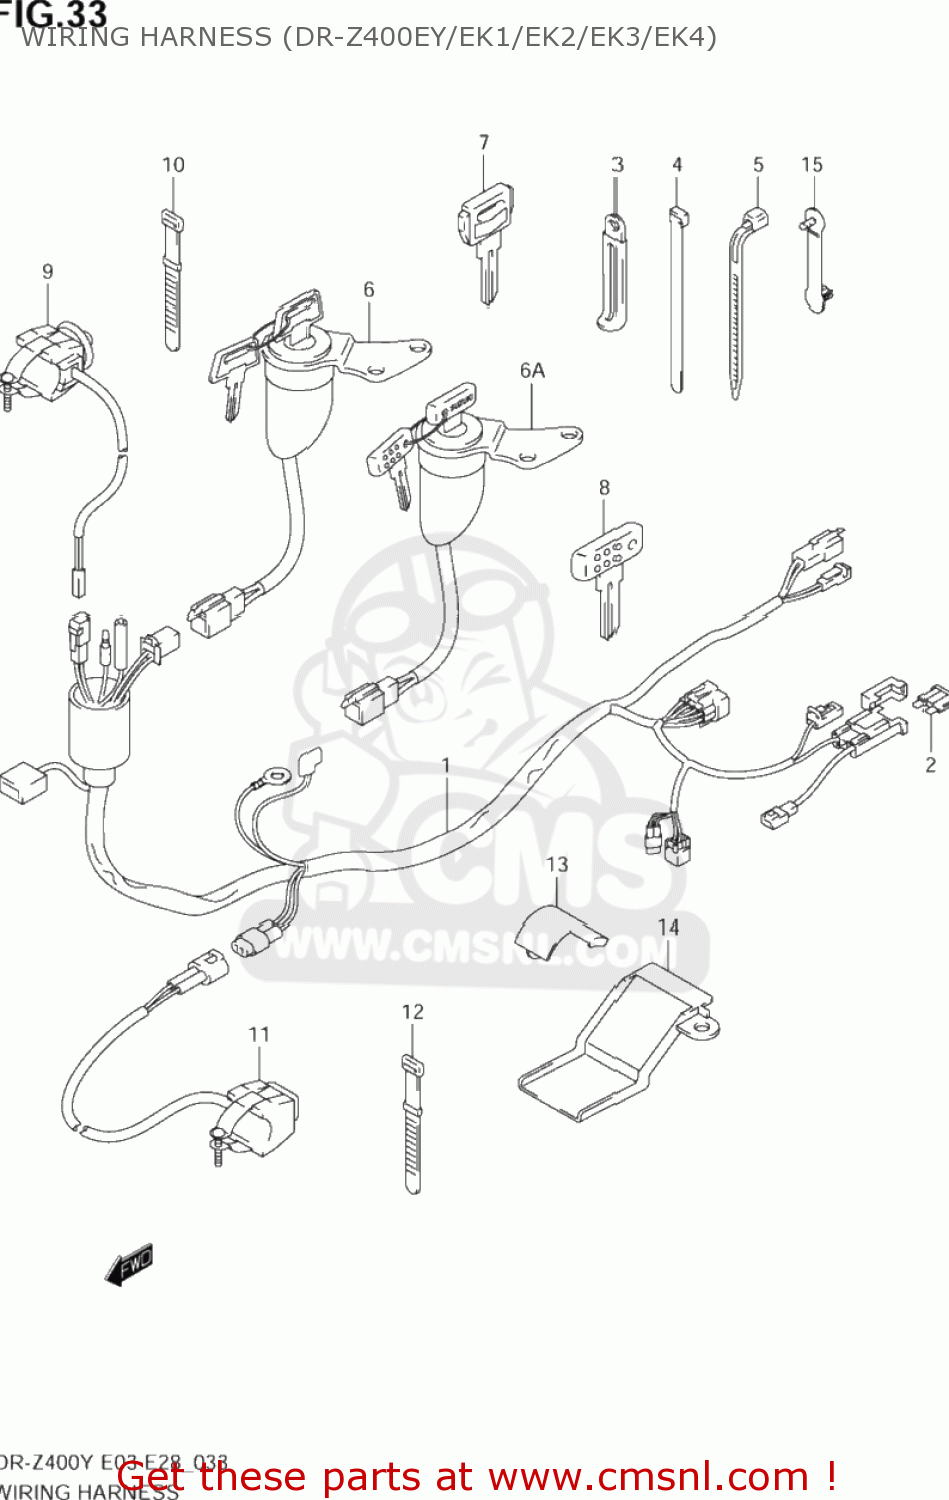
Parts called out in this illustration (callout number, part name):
1	HARNESS,WIRING
2	FUSE(10A)
3	CLAMP(L:45)
4	CLAMP(L:145)
5	CLAMP(L:125)
6	SWITCH ASSEMBLY,IGNITION
6A	SWITCH ASSY,IGNITION
7	KEY,BLANK(TYPE:C)
8	KEY,BLANK(TYPE:C)
9	SWITCH ASSY,STARTER
10	CLAMP(L:120)
11	SWITCH ASSY,ENGINE STOP
12	CLAMP(L:120)
13	PROTECTOR,WIRING HARNESS
14	PROTECTOR,WIRING HARNESS
15	CLAMP(L:63)
